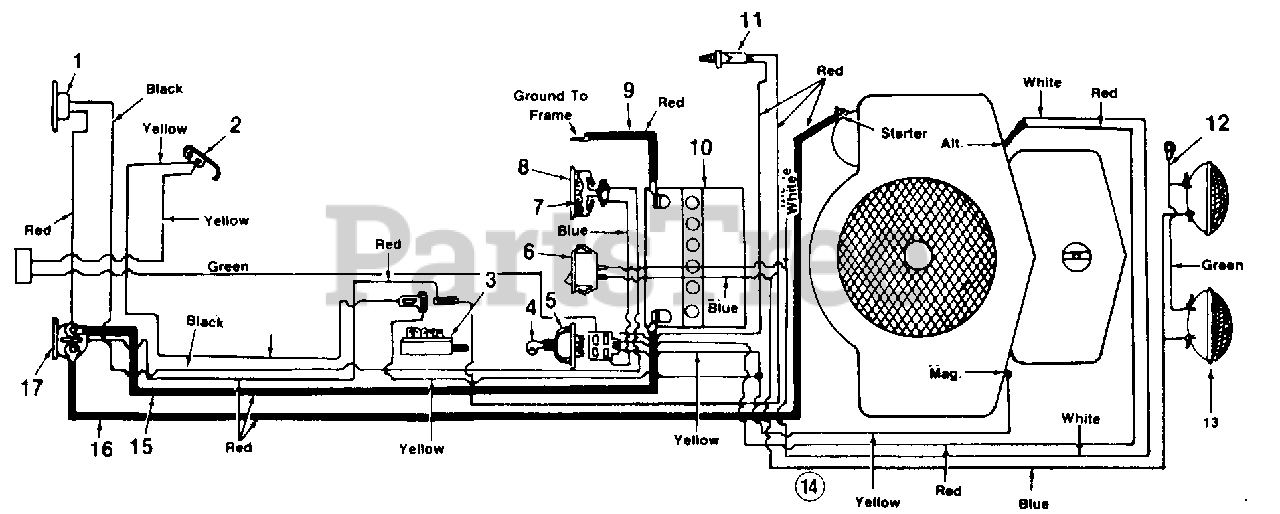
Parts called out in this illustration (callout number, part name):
1	Circuit Breaker
2	Spring Switch
3	Safety Switch Dpst.
4	Ignition Key
5	Ignition Switch
6	Headlight Switch
7	Foam Strip
8	Ammeter
9	Grounding Wire 14.0" Lg.
10	12 Volt Battery
11	Safety Switch
12	Ground Wire
13	Headlight
14	Wire Harness
15	Electric Wire 27.0" Lg.
16	Electric Wire 32.5" Lg.
17	Solenoid
